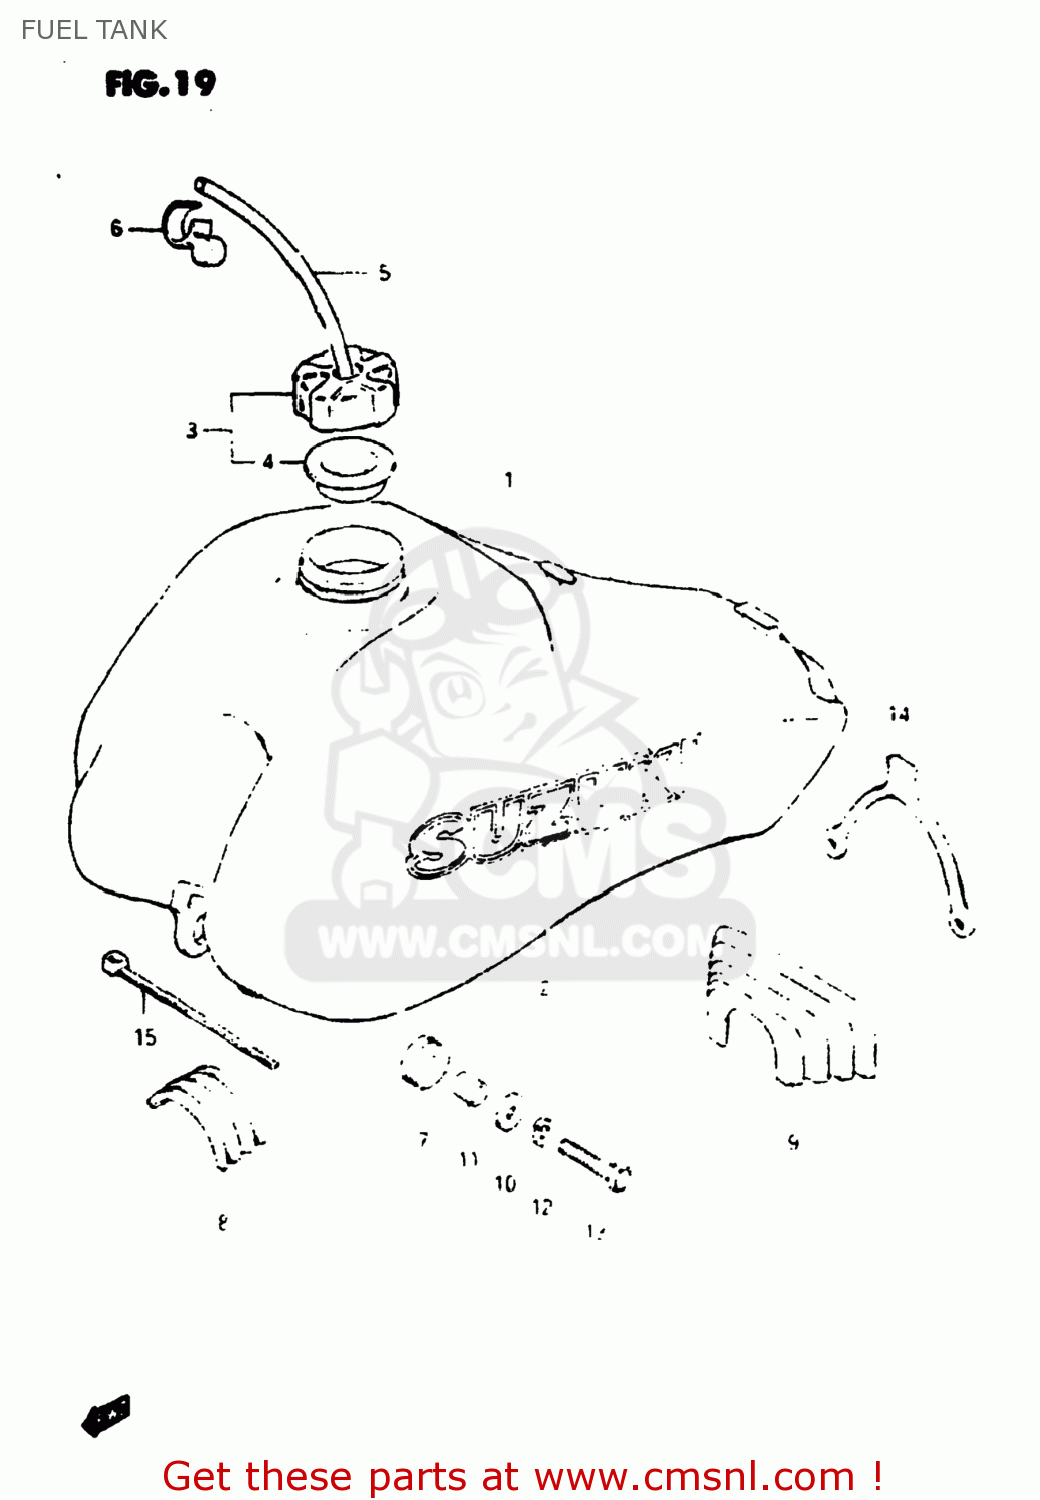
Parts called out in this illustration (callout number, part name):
1	TANK ASSEMBLY,FUEL
2	EMBLEM,REAR FENDER
3	CAP SET,FUEL TANK
4	GASKET,FUEL TANK CAP (NAS)
5	HOSE
6	CLAMP
7	CUSHION
8	CUSHION,FUEL TANK UPR FR
9	CUSHION,FUEL TANK UPR RR
10	WASHER (6.5X24X1.6)
11	SPACER (6.5X10.5X13.5)
12	LOCK WASHER
13	BOLT
14	BAND,FUEL TANK RR
15	CLAMP
